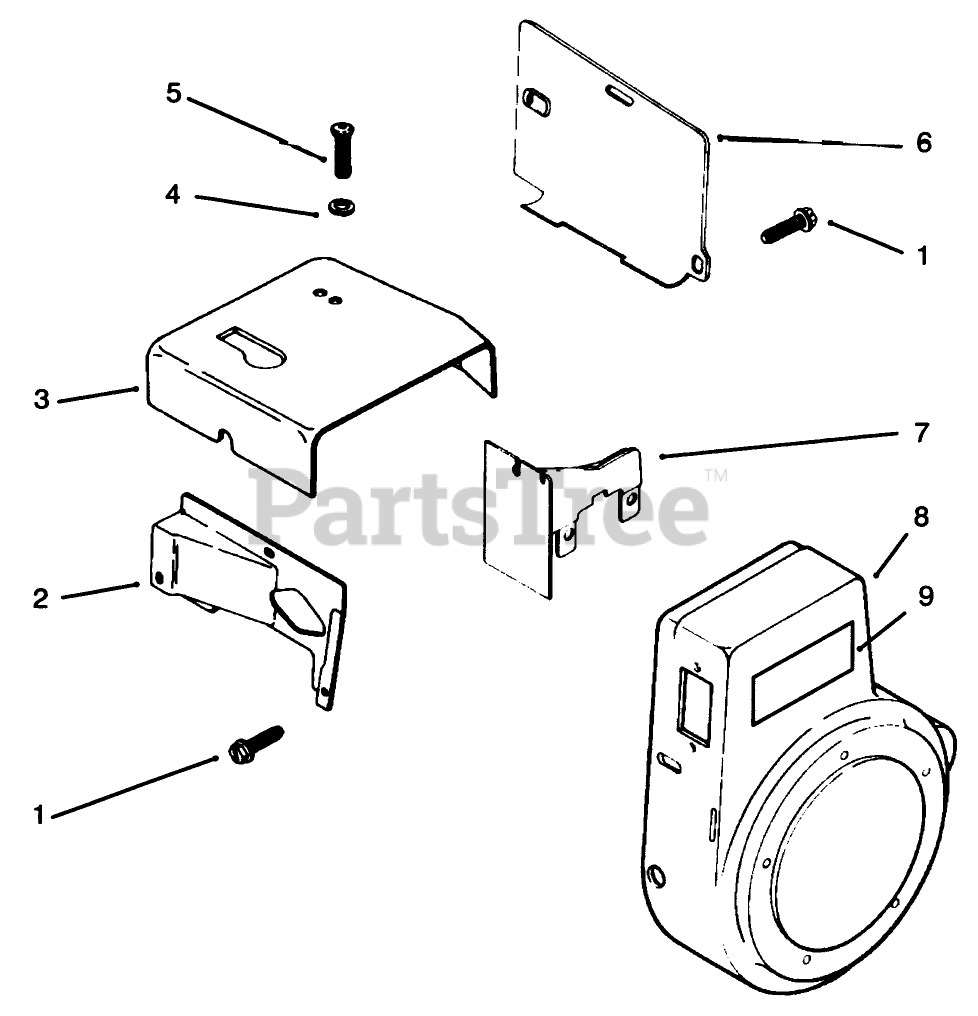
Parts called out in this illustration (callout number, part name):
1	KOHLER 52-086-11
2	KOHLER 47-063-06
3	KOHLER 45-063-08
4	KOHLER X-25-53
5	KOHLER 47-086-08
6	KOHLER 47-063-10
7	KOHLER 47-063-07
8	KOHLER 47-027-42
9	VNDR #47-113-36
